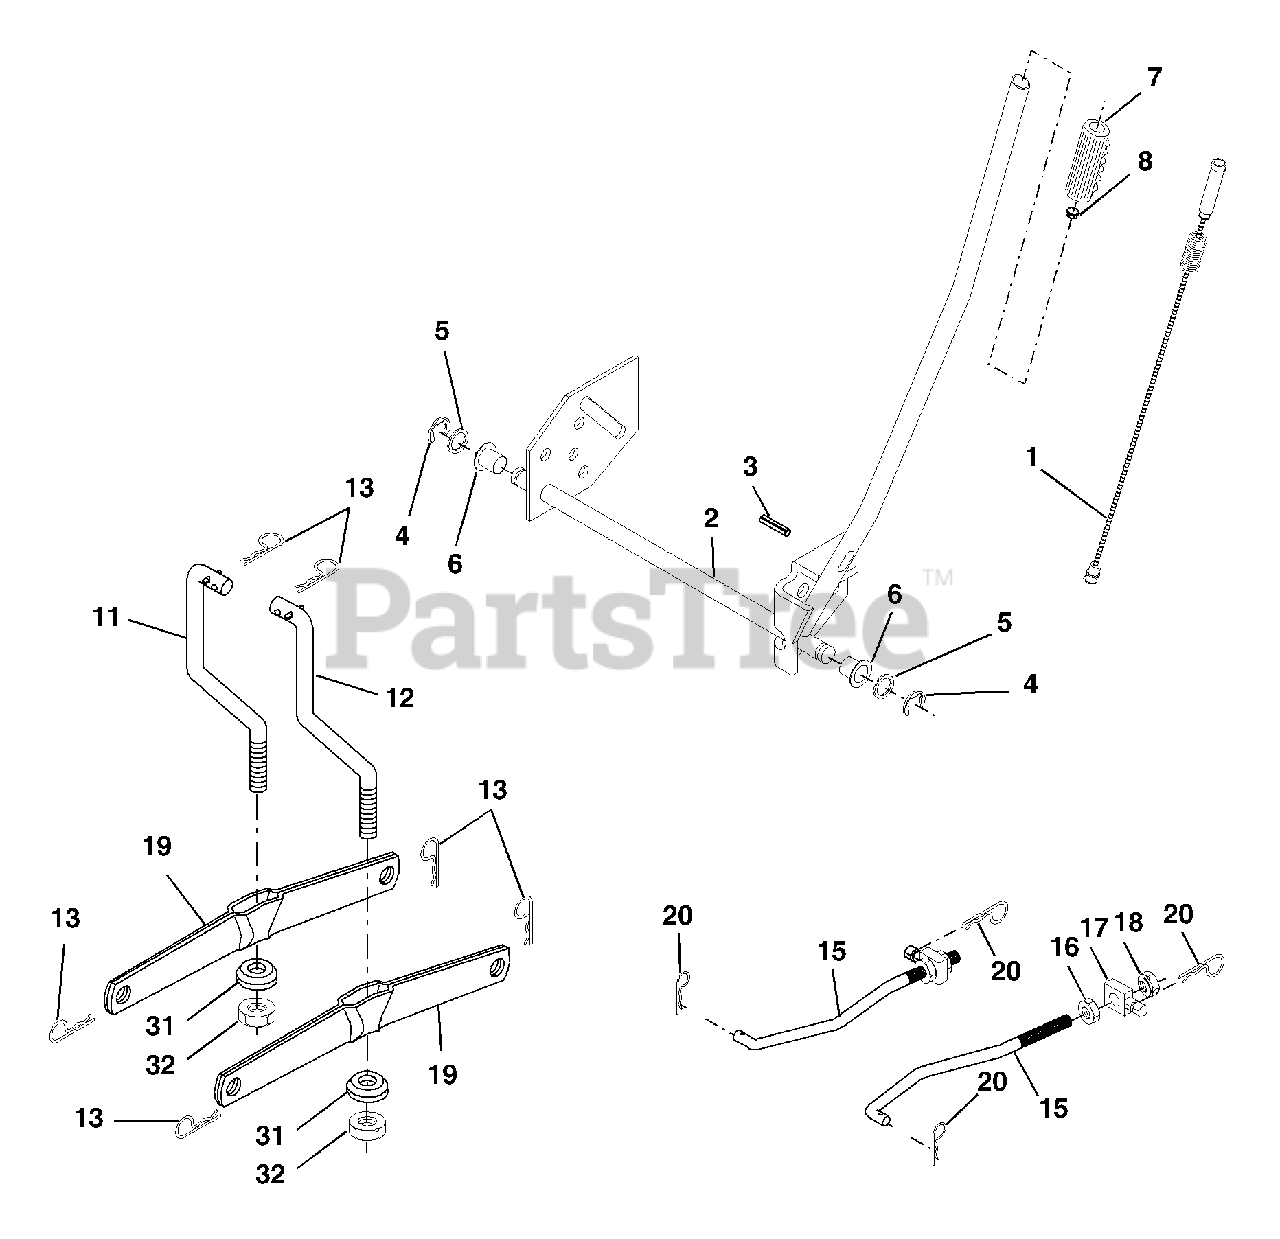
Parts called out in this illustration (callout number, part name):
1	Wire Asm Inner W/plunger
2	Shaft Asm Lift RH w/Inf
3	Pin Groove 1 500 Zinc
4	E Ring #5133-62
5	Washer 21/32 X 1 X 21 Ga
6	Bearing Nylon Blk 629 Id
7	Grip Handle Fluted Blk
8	Button Plunger Black
11	Link Lift LH Fixed Length
12	Link Lift RH Fixed Length
13	Retainer Spring
15	Link Front
16	Nut Jam Hex 1/2-13 Unc
17	Trunnion Blk Zinc
18	Nut Lock w/Wsh 1/2-13unc
19	Arm Suspension Rear
20	Retainer Spring
31	Bearing Pvt Lift
32	Nut Crownlock 3/8 - 24
